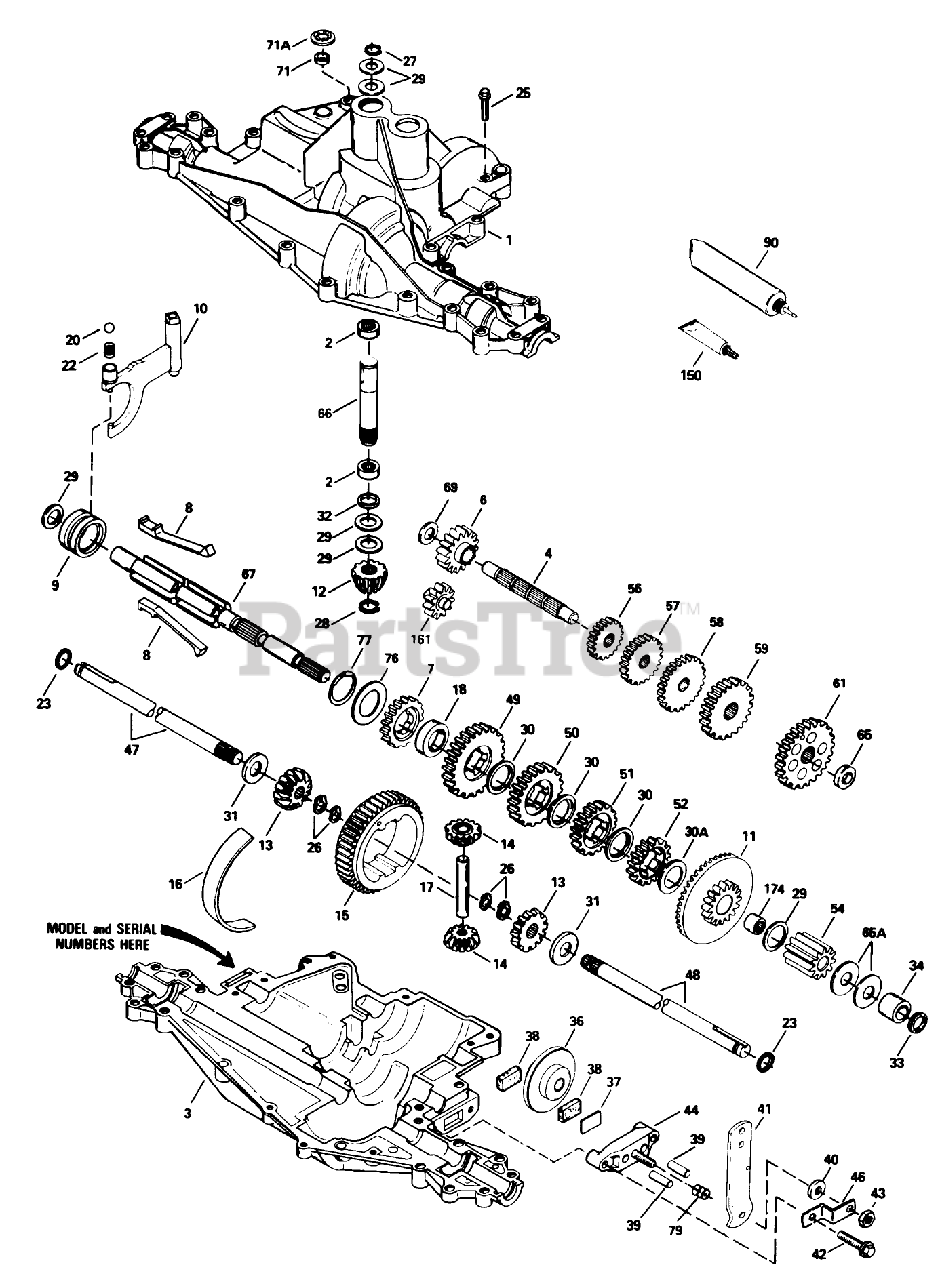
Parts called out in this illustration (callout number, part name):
1	Transaxle Cover
3	Transaxle Case
4	Countershaft
6	Spur Gear (16 Teeth)
7	Gear-Spur (22 teeth)
8	Shift Key
9	Shift Collar
10	Shift Rod Fork
11	Bevel Gear Bearing (44/16 Teeth) (Incl. Ref. #174)
12	Bevel Pinion (14 Teeth)
13	Gear Bevel
14	Gear Pinion
15	Gear-Ring
16	Bearing Strip
17	Drive Pin
18	Neutral Spacer
20	Ball (3/8" dia.)
22	Spring
23	Ring-Seal
25	Ring Set (.020 O S)
26	Retaining Ring (pkg of 2)
27	Ring-Snap
28	Ring-Retainer
29	Washer
30	Washer
30A	Washer
31	Washer
32	O Ring
33	O-Ring
34	Bushing
36	Brake Disk
37	Brake Pad Plate
38	Brake Pad
39	Dowel Pin
40	Washer
41	Brake Lever
42	Ring Set (.020 O S)
43	Locknut
44	Nozzle-Carburetor
46	Bracket
47	Axle (16-13/16" Ig.)
48	Axle (11-5/8" long)
49	Gear-Spur, 35 Teeth
50	Gear-Spur 27 Teeth
51	Spur Gear (19 Teeth)
52	Gear-Spur 20 teeth
54	Spur Gear (11 Teeth)
56	Gear-Spur, 15 Teeth
57	Gear-Spur 23 Teeth
58	Spur Gear (21 Teeth)
59	Gear-Spur (30 teeth)
61	Spur Gear (34Teeth)
65	Washer
65A	Washer
66	Input Shaft (3.522" Ig.)
67	Shifter Brake Shaft
69	Thrust Washer
71	Cut Seal-Square
71A	Pushnut
76	Washer
77	Inverted Retaining Ring
79	Piston ASM (.020 O S)
90	Grease 32 Oz
150	Gasket Eliminator
161	Reverse Idler Assembly
174	Needle Bearing
